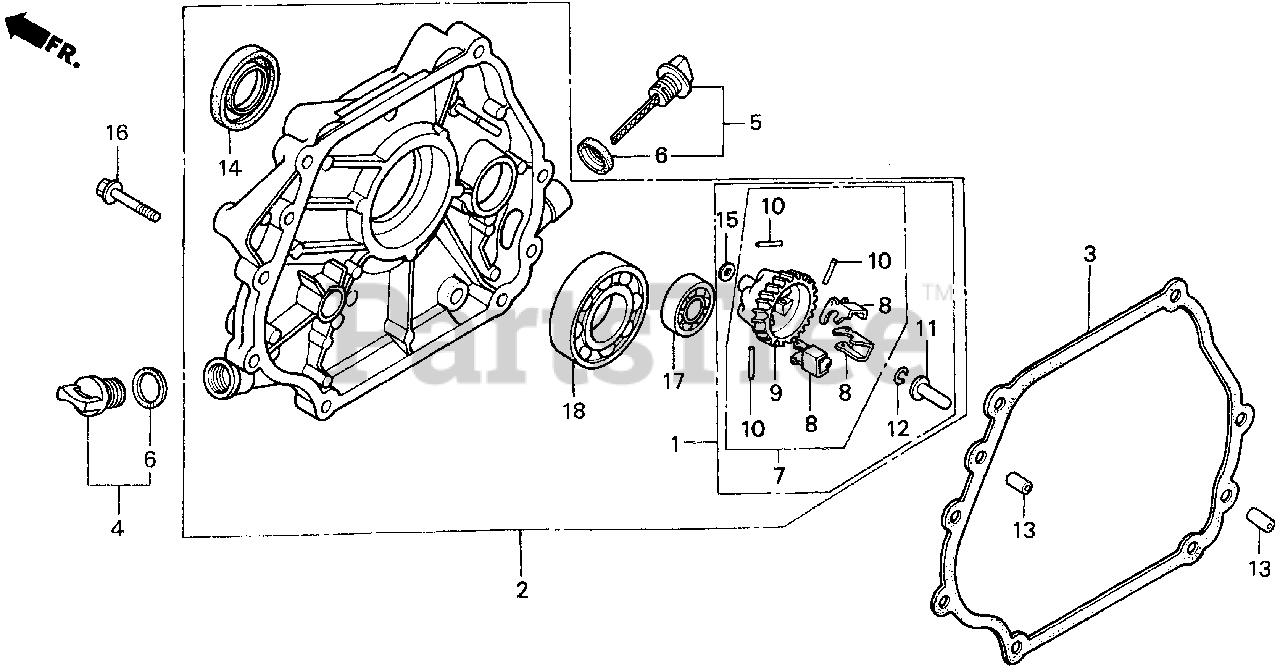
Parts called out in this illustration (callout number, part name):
1	GOVERNOR KIT (STD)
2	COVER ASSY., CRANKCASE (S-TYPE)
2	COVER ASSY., CRANKCASE
3	GASKET, CASE COVER
4	CAP ASSY., OIL FILLER
5	CAP ASSY., OIL FILLER
6	GASKET, OIL FILLER CAP
7	GOVERNOR ASSY. (STD)
8	WEIGHT, GOVERNOR
9	HOLDER, GOVERNOR WEIGHT
10	PIN, GOVERNOR WEIGHT
11	SLIDER, GOVERNOR
12	CLIP, GOVERNOR HOLDER
13	PIN, DOWEL (8X12)
14	OIL SEAL (30X46X8)
15	WASHER, PLAIN (6MM)
16	BOLT, FLANGE (8X35)
18	BEARING, RADIAL BALL (6206)
